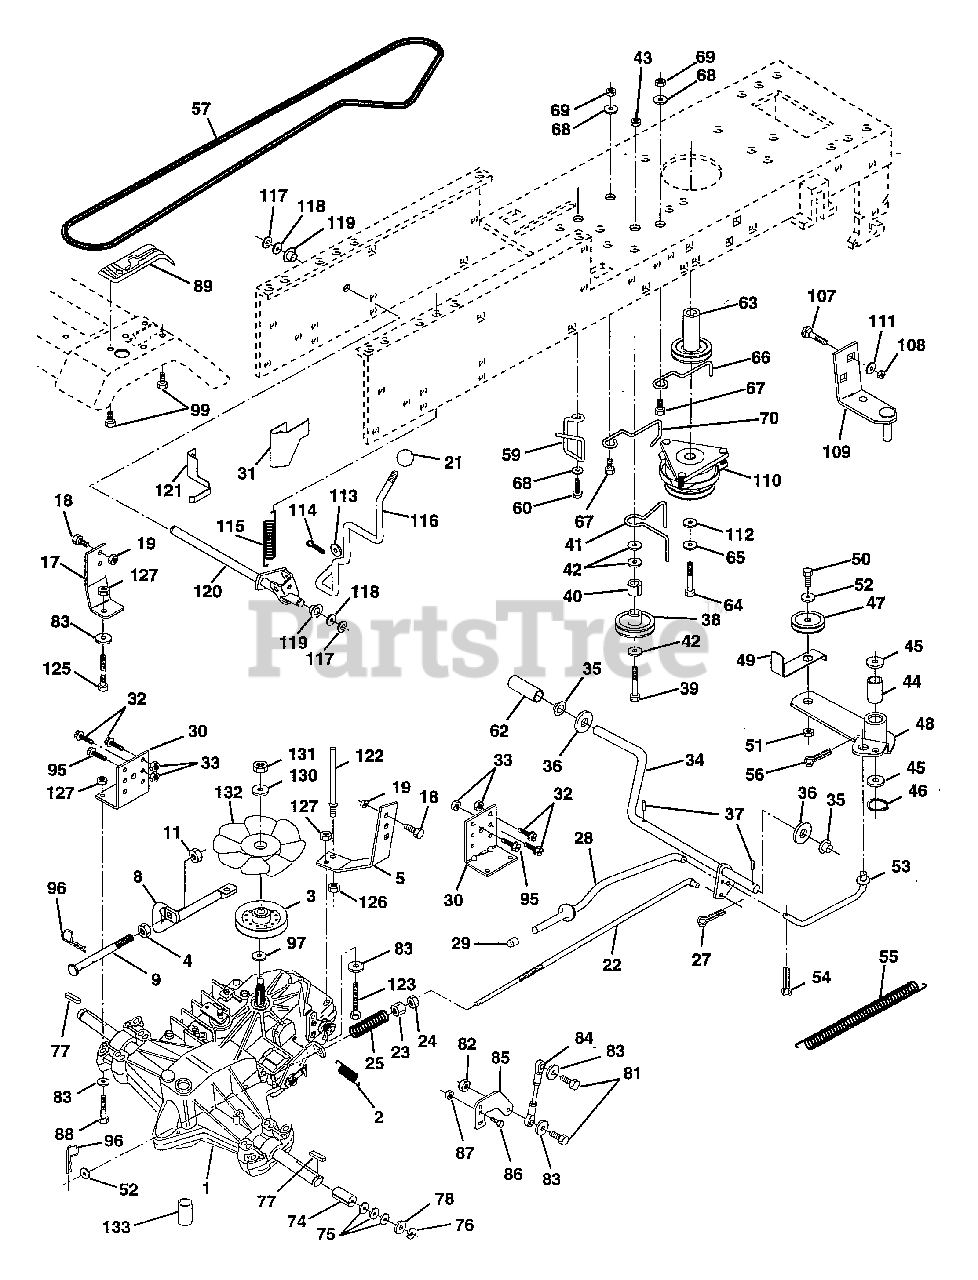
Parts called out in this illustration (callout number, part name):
1	Transaxle Assembly
2	Spring, Return, Brake
3	Pulley, Transaxle
4	Nut Hex Jam 5/16-18 Unc
5	Strap Torque Rh Hydro 18/20" T
8	Control Bypass Hydro 18" Tires
9	Rod Bypass Hydro 18/20"
11	Nut Lock Hex W/Ins 5/16-18 Unc P
17	Strap Torque Lh Hydro 18/20" T
18	Bolt Fin Hex 3/8-16 Unc x 1 Gr. 5
19	Nut Lock Hex W/Wsh 3/8-16 Unc
21	Knob, Duckhead 1/2-13
22	Rod, Brake Hydro
23	Nut
24	Locknut
25	Spring, Brake Rod
27	Pin Cotter 1/8 x 3/4 CAD.
28	Rod, Parking Brake
29	Cap, Parking Brake
30	Bracket, Transaxle
31	Keeper Belt Lh
32	Bolt Hex Hd 5/16-18 Unc x 3/4
33	Nut Lock Hex W/Ins. 5/16-18 Unc
34	Shaft, Foot Pedal
35	Bearing, Nylon
36	Washer
37	Pin, Roll
38	Pulley, Idler, Flat
40	Spacer, Split
41	Keeper, Belt Retainer
42	Washer 13/32 x 13/16 x 12 Gauge
43	Nut
44	Bearing, Nylon
45	Washer, Hardened
46	Ring, Klip
47	Pulley, Idler, V-Groove
48	Bellcrank Assembly
49	Retainer, Belt
50	Bolt
52	Washer
53	Link, Clutch
54	Pin
55	Spring, Return, Clutch
56	Pin
57	V-Belt, Ground Drive
59	Keeper, Center Span
60	Screw Thdrol. 3/8-16 x 3/4 Ty. TT
62	Cover, Pedal
63	Pulley, Engine
64	Bolt, Hex
65	Washer
66	Keeper Belt Engine
67	Bolt
68	Washer 13/32 x 13/16 x 12 Gauge
69	Nut
70	Keeper Belt Engine
74	Spacer, Split
75	Washer 25/32 x 1-1/4 x 16 Gauge
77	Key, Square
78	Washer 25/32 x 1-5/8 x 16 Gauge
81	Bolt Fin Hex 5/16-18 Unc x 1-1/4
82	Nut Lock Hex W/Ins. 5/16-18 Unc P
83	Washer 11/32 x 3/4 x 16 Ga.
84	Rod, Tie Hydro 20" Tires
85	Arm, Control Hydro
86	Screw Cap Hex 5/16 x 18 x 1
87	Nut Lock Hex W/Ins. 5/16-18 Unc P
88	Bolt Fin Hex 5/16-18 Unc
89	Console, Shift
95	Screw, Thdroll. 3/8-16 x 1 Type TT
96	Retainer Spring 1" Zinc/Cad
97	Washer 21/32 x 1 x 16 Ga.
99	Screw
107	Bolt Carriage 5/16-18
108	Nut, Crownlock 5/16-18
109	Bracket, Asm Mtg Clutch
110	Clutch, Electric
111	Washer 11/32 x 5/8 x 12 Ga.
112	Washer 1-1/2 OD x 15/32 ID x .250
113	Washer 17/32 x 3/4 x 16 Ga.
114	Pin Cotter 1/8 x 1 CAD
115	Spring Torsion T/A
116	Rod Shift Fender YT
117	Ring Klip #5304-62
118	Washer 21/32 x 1-1/4 x 16 Ga.
119	Bushing Rod Steering 629/632 ID
120	Shaft Asm. Cross Hydro 20" Tires
121	Keeper Belt Lh Hydro 0750. 18/20"
122	Keeper Belt Rh Hydro 0750. 18/20"
123	Bolt Fin Hex 5/16-18 x 2-1/4
125	Bolt Fin Hex 5/6-18 Unc x 1-1/2
126	Nut Keps Hex 3/8-16 Unc
127	Nut Lock Hex W/Ins 5/16-18 Unc P
130	Washer Belleville .501D x 1.50D
131	Nut Nylon Insert 1/2-20 Unf.
132	Fan, Hydro 7"
133	Line Fuel Hydro 4"
